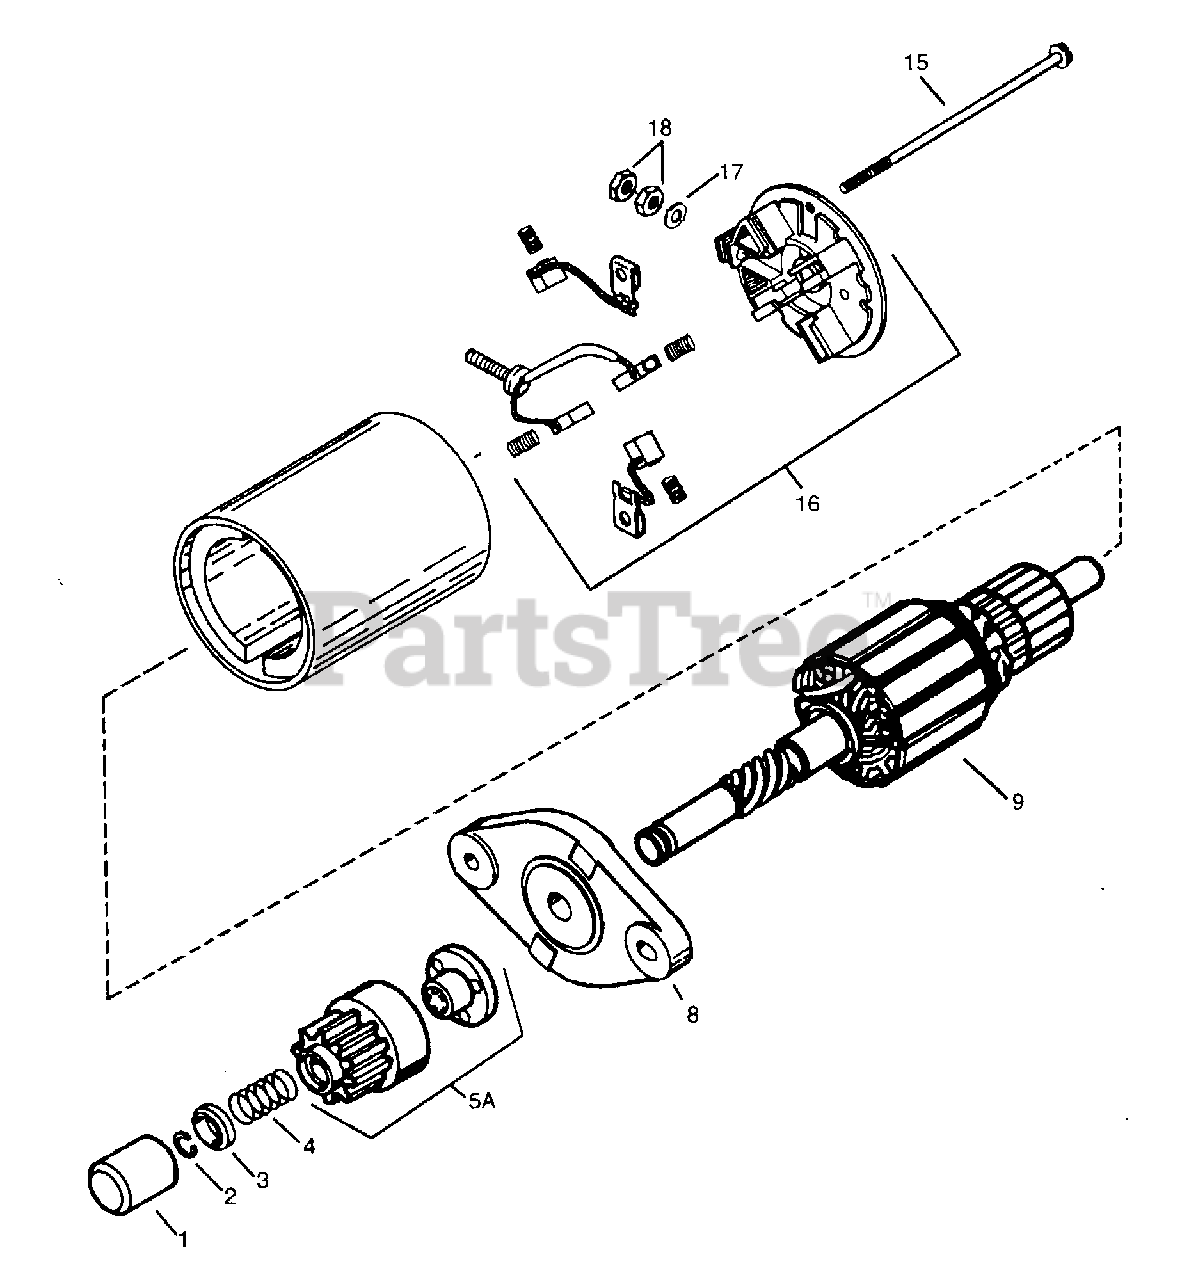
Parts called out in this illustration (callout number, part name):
1	Dust Cover
2	Retainer Ring
3	Spring Retainer
4	Anti-drift Spring
5A	Gear & Nut (Incl. 2)
8	Drive End Cap Assembly
9	Armature
14	Thrust Washer
15	Case Bolt
16	End Cap & Brush Card Ass'y Incl. 14,1 7 & 18
